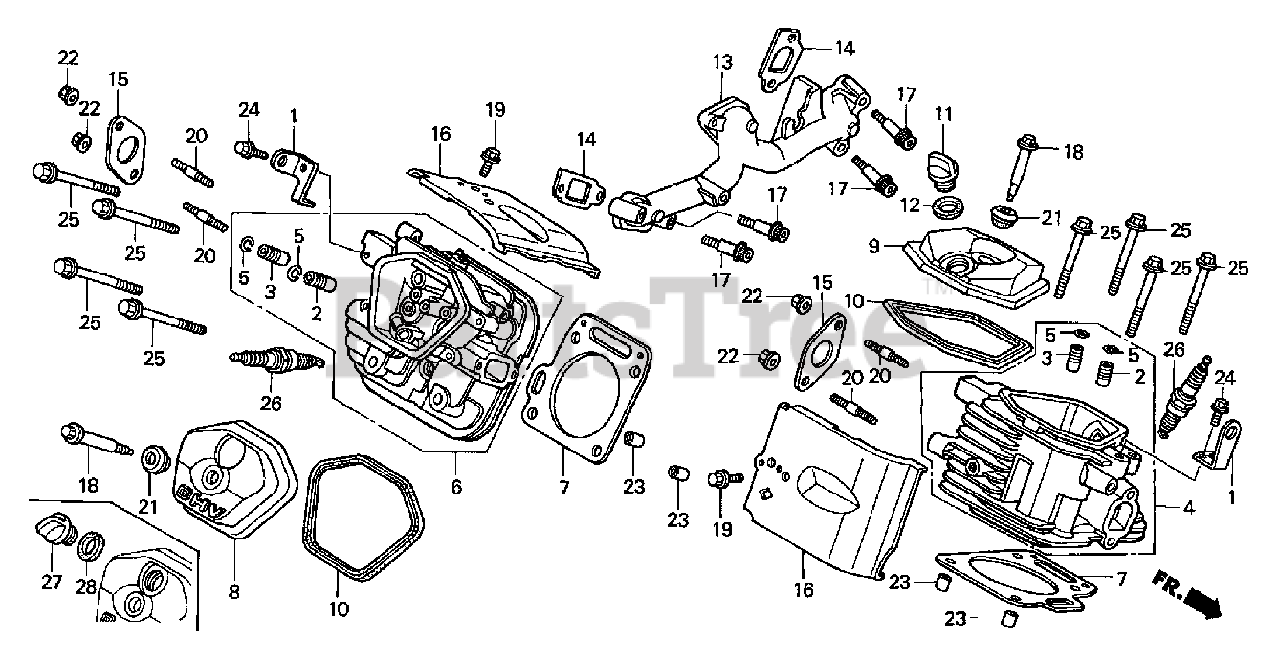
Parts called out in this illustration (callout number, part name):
1	Hanger, Engine
2	Guide, Valve (OS)
3	Guide, Ex. Valve (OS)
4	Cylinder Head (#1)
5	Clip, Valve Guide
6	Cylinder Head (#2)
7	Gasket, Cylinder Head
8	Cover, Head
9	Cover, Head Filler
10	Gasket, Cylinder Head Cover
11	Cap, Oil Filler
12	Gasket, Oil Filler Cap
13	Manifold, In
14	Gasket, In. Manifold
15	Gasket, Ex. Pipe
16	Shroud, Head
17	Bolt, Socket (8x45)
18	Bolt, Head Cover
19	Bolt, Flange (6x14)
20	Bolt, Stud (8x22)
21	Washer, Head Cover
22	Nut, Flange (8mm)
23	Pin A, Dowel (12x20)
24	Bolt, Flange (8x20)
25	Bolt, Flange (10x80)
26	Spark Plug (BPR2ES) (NGK)
